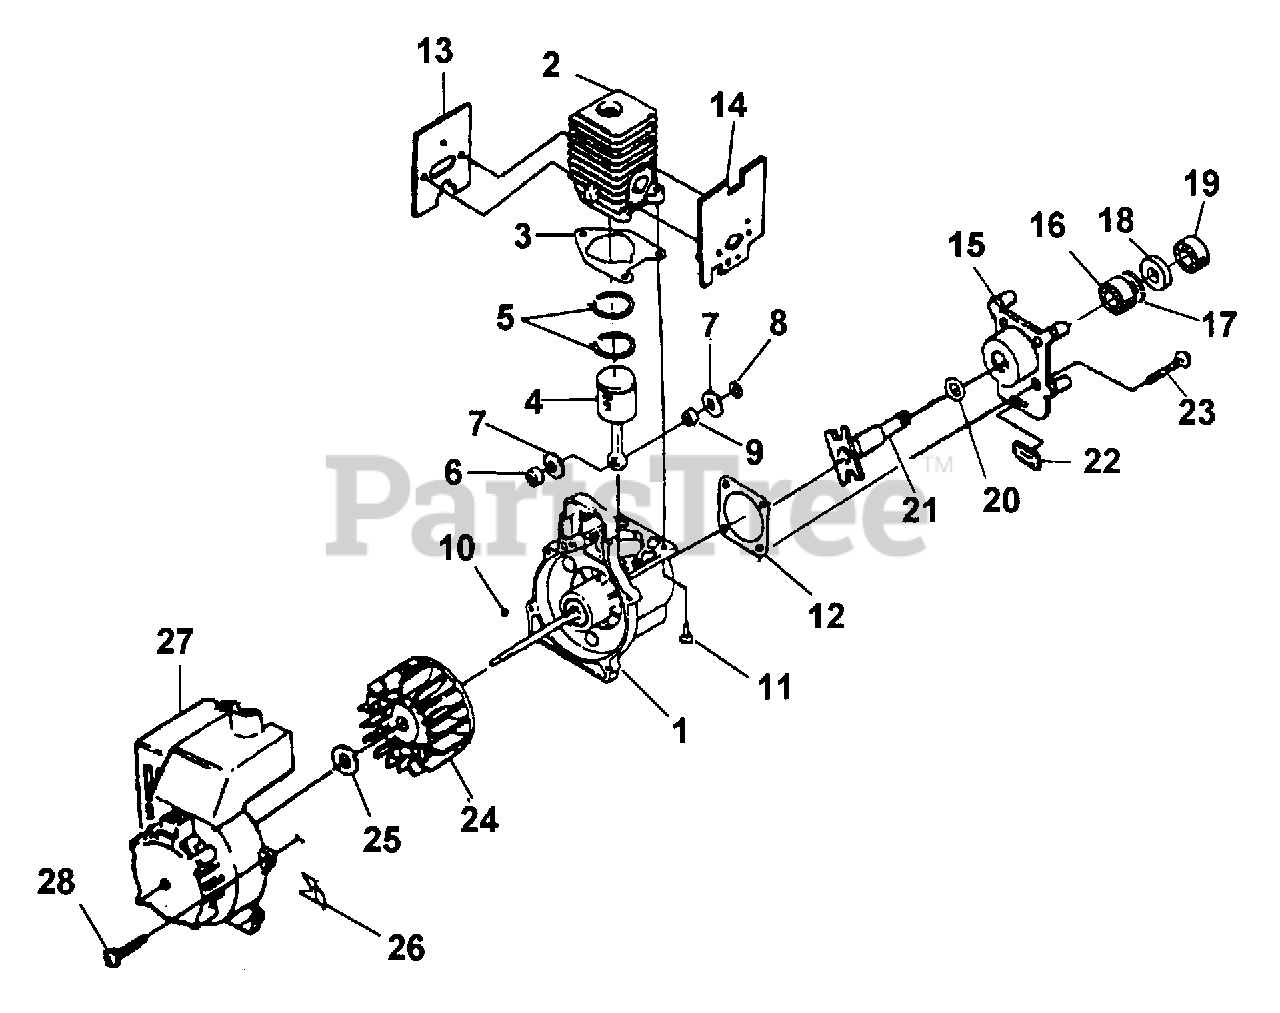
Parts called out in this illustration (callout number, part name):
1	SHORT BLOCK
2	CYLINDER & GASKET
3	GASKET, CYLINDER
4	PISTON & ROD
5	RING, PISTON
6	SPACER, BEARING
7	THRUST WASHER
8	RETAINING RING
9	BEARING, NEEDLE
10	KEY, WOODRUFF
11	SCREW,TORX PAN HEAD 12-24 X 3/4
12	GASKET CRANKCASE
13	GASKET, MUFFLER
14	GASKET, HEAT DAM
15	COVER, CRANKCASE
16	BEARING, BALL
17	RETAINING RING
18	SEAL, SHAFT
19	BEARING, BALL
21	SHAFT, STARTER
23	SCREW, SELF TAPPING 10-24 X 3/4
24	ROTOR
25	WASHER, FLAT
26	TAB, MALE
27	ENGINE HOUSING W/DECALS
28	SCREW, SELF TAPPING 10-24 X 3/4
